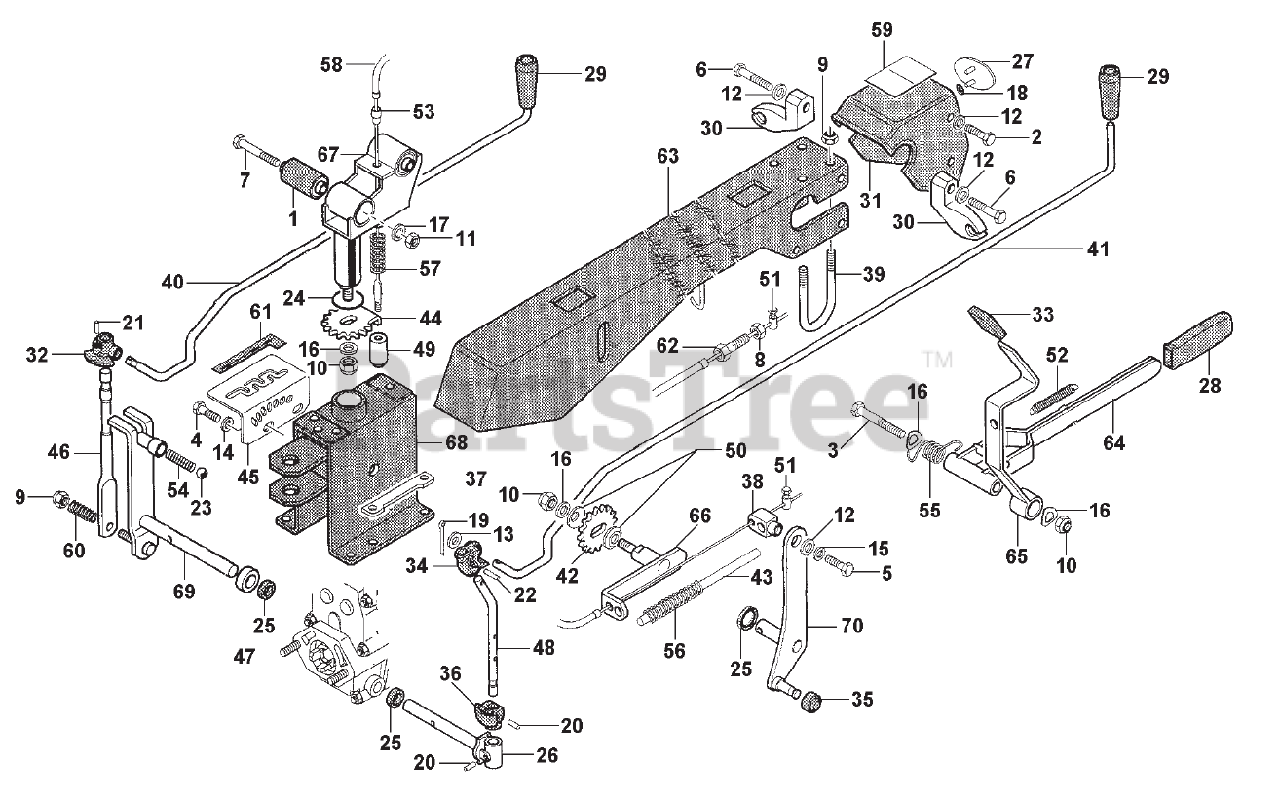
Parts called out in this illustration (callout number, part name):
1	SILENTBLOCK
2	SCREW,M8X16
3	SCREW,M10X90
4	SCREW,M8X14
5	SCREW,M8X12
6	SCREW,M8X35
7	SCREW,M12X95
9	NUT,SELFLOCKING,M8
10	NUT,SELFLOCKING,M10
11	NUT,SELFLOCKING,M12
12	WASHER,FLAT,M8.4
14	WASHER,M8.4
15	WASHER,LOCK,M8.4
16	WASHER,LOCK,M10.5
17	WASHER,LOCK,M13
18	WASHER,LOCKFORPINS
20	LOCKINGPIN,M4X20SPIRAL
21	PIN,LOCKING,M3X22SPIRAL
22	LOCKINGPIN,M4X24SPIRAL
23	BALL 15/32 RIV RB-11.906
24	O-RING,M28.17X3.53
25	OILSEAL,M14X22X4
30	SUPPORTCONTROLRODCUT
31	STEERINGCOLUMNINTERM.PANEL
32	GEARBOXARTICULATION
33	KNOBREDUCTIONUNITLEVER
34	PTOARTICULATION
35	PTOLOCKOUTRING
36	PTOSTOPRING
37	REVERSESPEEDLEVERDOG
38	REVERSEBLOCK
39	HANDLEBARU-BOLT
40	GEARBOXCONTROLROD
41	PTOCONTROLROD
42	REVERSEGEAR
44	BENDEDREVERSERGEAR
45	GEARQUADRAINT
48	PTOCONTROLLEVER
50	PROTECTIONENDD32
51	CLAMP,CABLE
55	HANDLEBARRELEASESPRING
56	REVERSERSPRING
57	PUSHRODSPRING
58	STEERINGCOLUMNCABLE
59	STEERINGCOLUMNSTICKER
62	ADJUSTINGSCREW
63	STEERINGCOLUMN
64	HANDLEBARRELEASELEVER
65	STEERINGCOLUMNLOCKINGLEVER
66	REVERSERPOSTIONLEVER
67	STEERINGCOLUMNCOUPLING
68	STEERINGCOLUMNSUPPORT
69	SPEEDSELECTORLEVER
70	REVERSERLEVER
